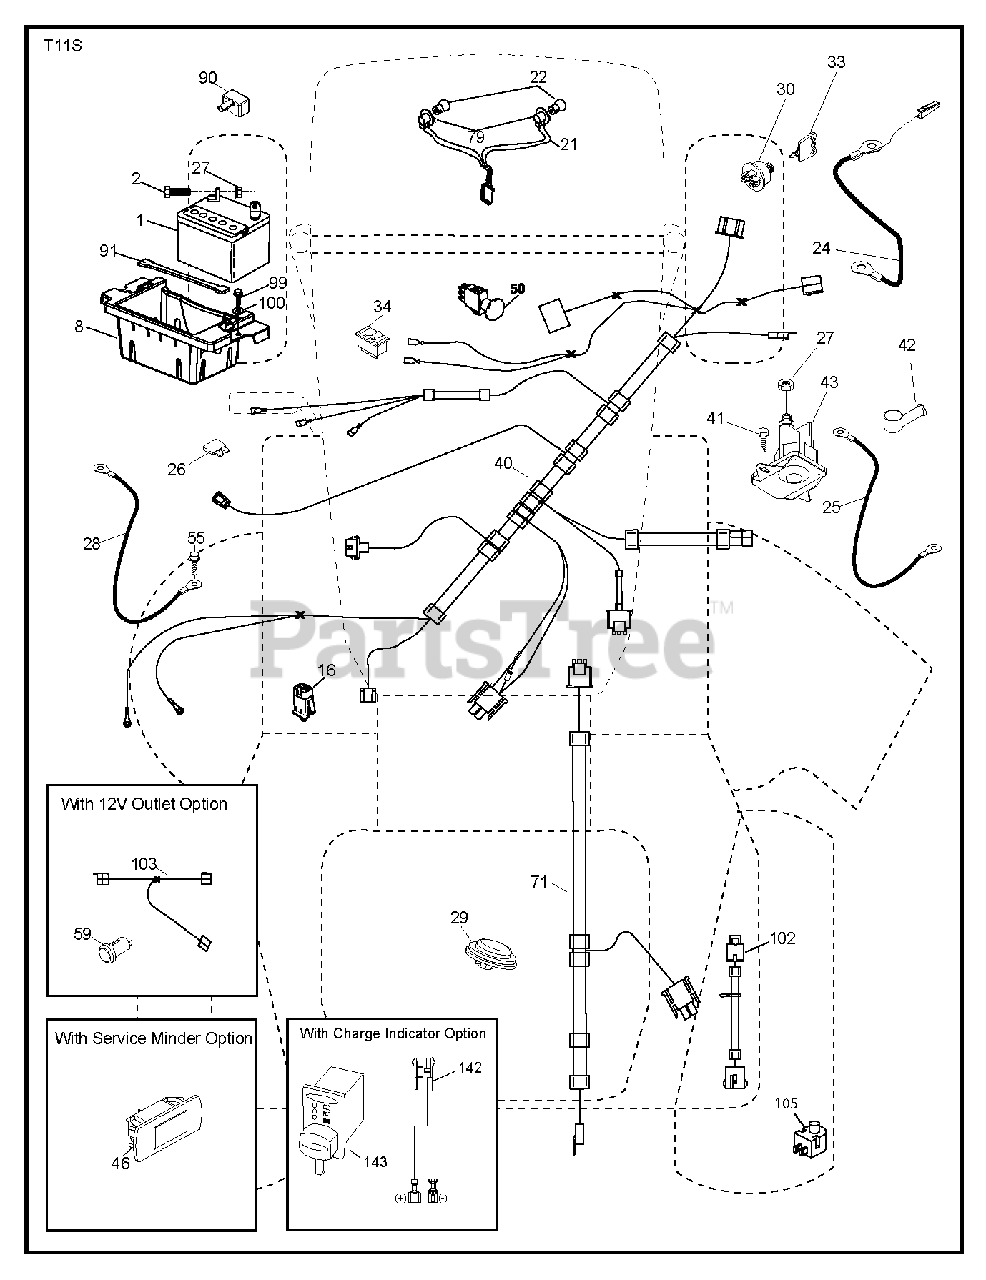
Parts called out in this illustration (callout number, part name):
1	REPL BY 532 12 38-99
2	BOLT.HEX.1/4.X.3/4.DICHROMATE
8	BOX.BATTERY.MOUNT.FRONT.LT
16	SWITCH INTERLOOK PUSH-IN
21	HARNESS ASSY LIGHT
22	LIGHTBULB
24	CABLE.BATT.POS.WIRE.TG.DA SOL
25	CABLE.STARTER.6G.BL/RED.17.5
26	FUSE 20AMP
27	NUT
28	CABLE GROUND 6 GA 21" 90T BLK
29	SWITCH.SEAT.DELTA.OPC.
30	SWITCH.IGN.DELTA.W.LGH.ROS
33	KEY.CHAIN.BLISTER.PACK.GEN.INT
34	SWITCH LT
40	HARNESS.IGN.DASH.HUQ/P
41	SCREW
42	TERMINAL COVER
43	SOLENOID.W/BRASS.PLUNGER
46	GUAGE.SRVCMNDR.HRMTR.
50	PTO SWITCH
55	SCREW 5/16"
71	HARNESS-CHASSIS SUB
79	BULB HOLDER ASM.
90	COVER.TERMINAL.BATTERY
91	STRAP.BATTERY.MOUNT.FRONT
99	SCREW HEXWSHR 1/4-20X3/4
102	HARNESS PIGTAIL PCH TEX ROS
105	REVERSE SWITCH
